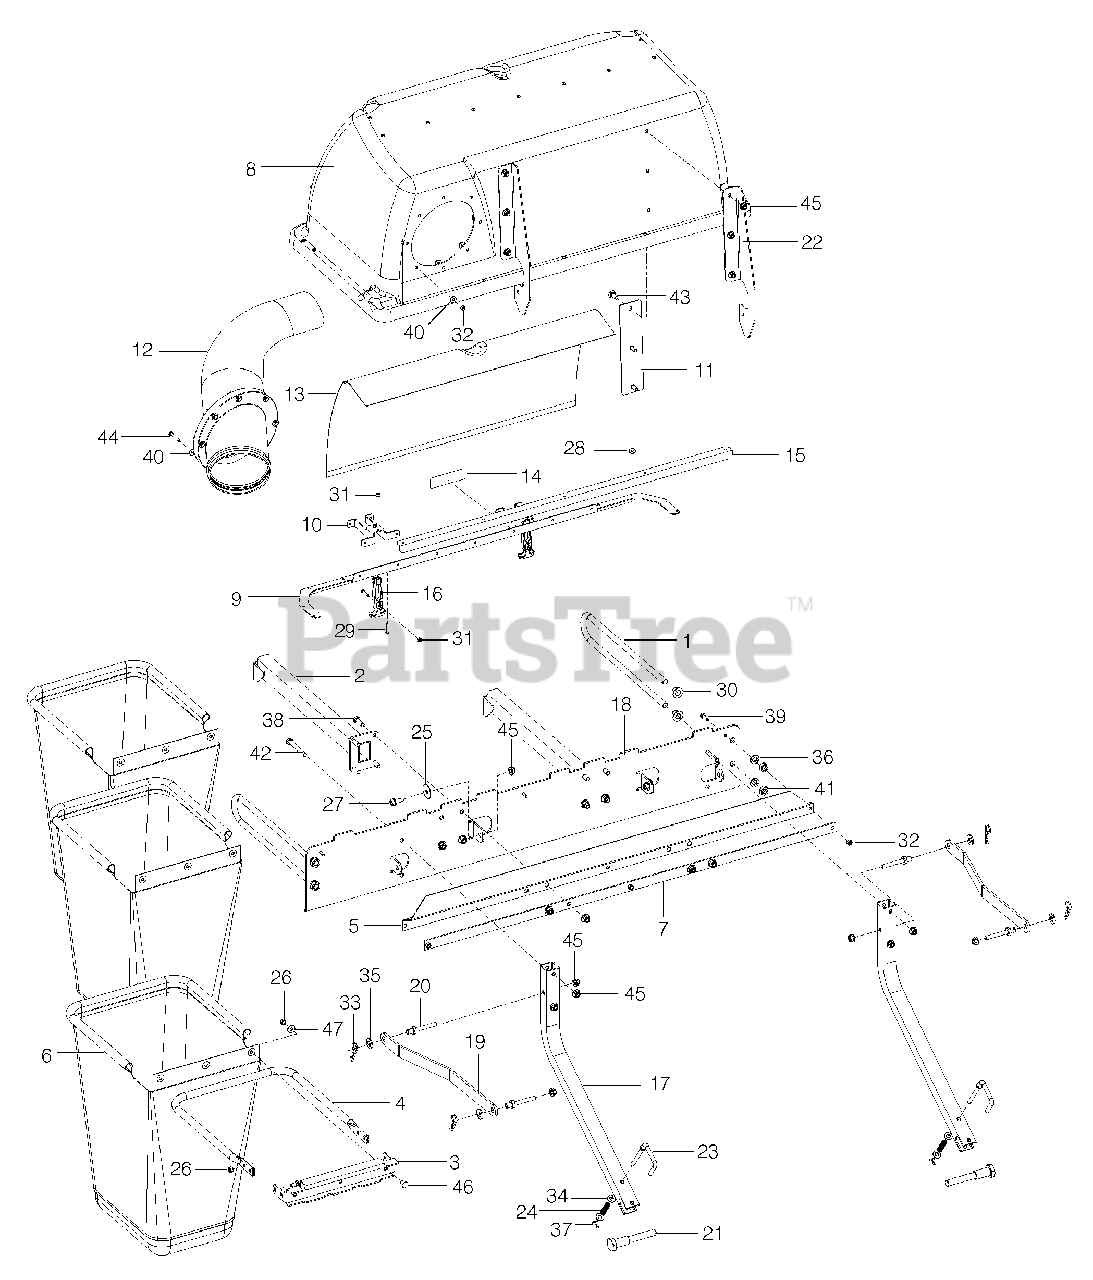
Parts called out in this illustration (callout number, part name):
1	Support, Outer
2	Arm, Support
3	Hanger, Bag
4	Tube, Bag Frame
5	Seal, Rubber
6	Bag, Large
7	Seal Strap
9	Support, Hood
10	Support, Draw Latch
11	Plate, Hood Mount
12	Inlet Tube
13	Mesh, Poly Diamond
14	Decal, Ventilation
15	Hood Support, Rear
16	Draw Latch
17	Tube, Hitch
18	Plate, Hitch Mount
20	Pin, Mount
21	Bolt, Pivot
22	Bracket, Hinge
23	Pin, Retention
24	Spring, Compression
25	Friction Washer
26	Nut 5/16-18 Nyloc
27	Bolt 3/8-16 X 1 Thd Frm
28	Washer #10 Mach Scr
29	Screw #10-24 X 11/8 Mach
30	Nut 1/2-13 Hex Whizlk
31	Nut #10-24 Hex Nyloc
32	Nut 1/4-20 Hex Nyloc
34	Washer 3/8 Sae Flt
36	Washer 1/2 Slw
37	Pin, Cotter 1/8 X 3/4
38	Hcs 3/8-16 X 1
39	Hcs 1/4-20 X 3/4
40	Washer 1/4 Flat
41	Nut 1/2-13 Hex Jam
42	Hcs 3/8-16 X 2 1/4
43	Rhsnb 3/8-16 X 1
44	Hcs 1/4-20 X 1 3/4
45	Nut 3/8-16 Hex Flg Nyloc
46	Rhsnb 5/16-18 X 3/4
47	Washer 5/16 Flat
